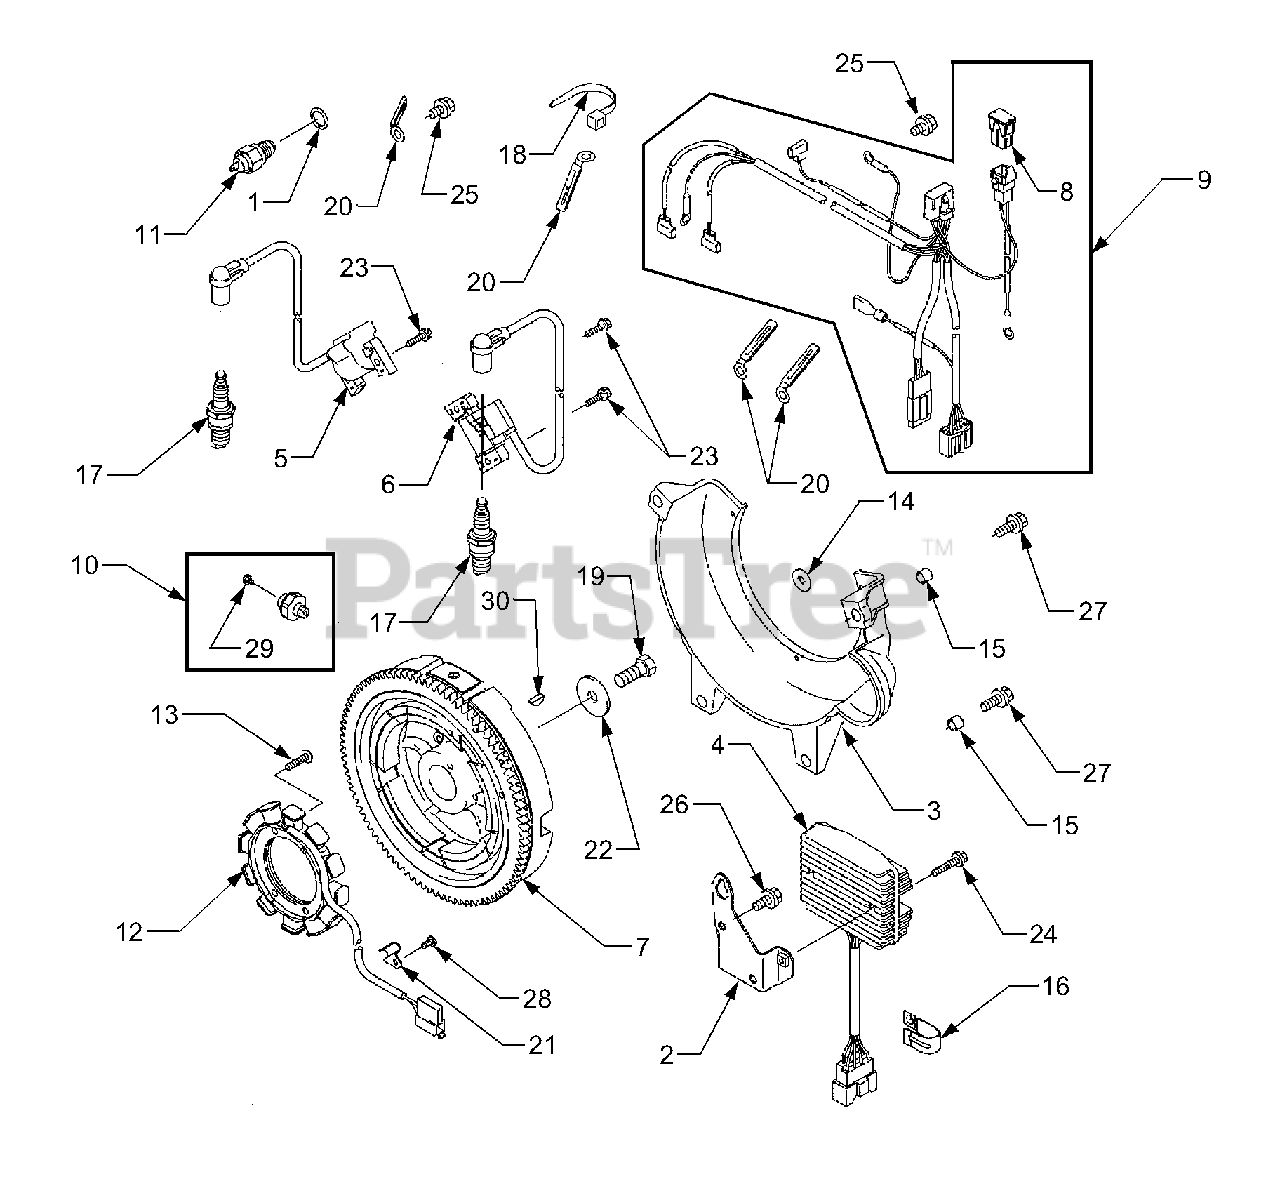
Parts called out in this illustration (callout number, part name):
3	Cover, Flywheel
4	Regulator, Voltage
5	Coil, Ignition, No. 1
6	Coil, Ignition, No. 2
7	Flywheel Assembly
9	Harness
10	Switch
12	Coil, Charging
15	Collar, 8.3 x 11.5 x 9
17	Plug, Spark
19	Bolt, 12 x 30
22	Washer, 12.2 x 40 x 3.0
23	Bolt, Flanged
24	Bolt, Flanged
25	Bolt, Flanged
26	Bolt, Flanged
27	Bolt, Flanged
30	Key, Woodruff
